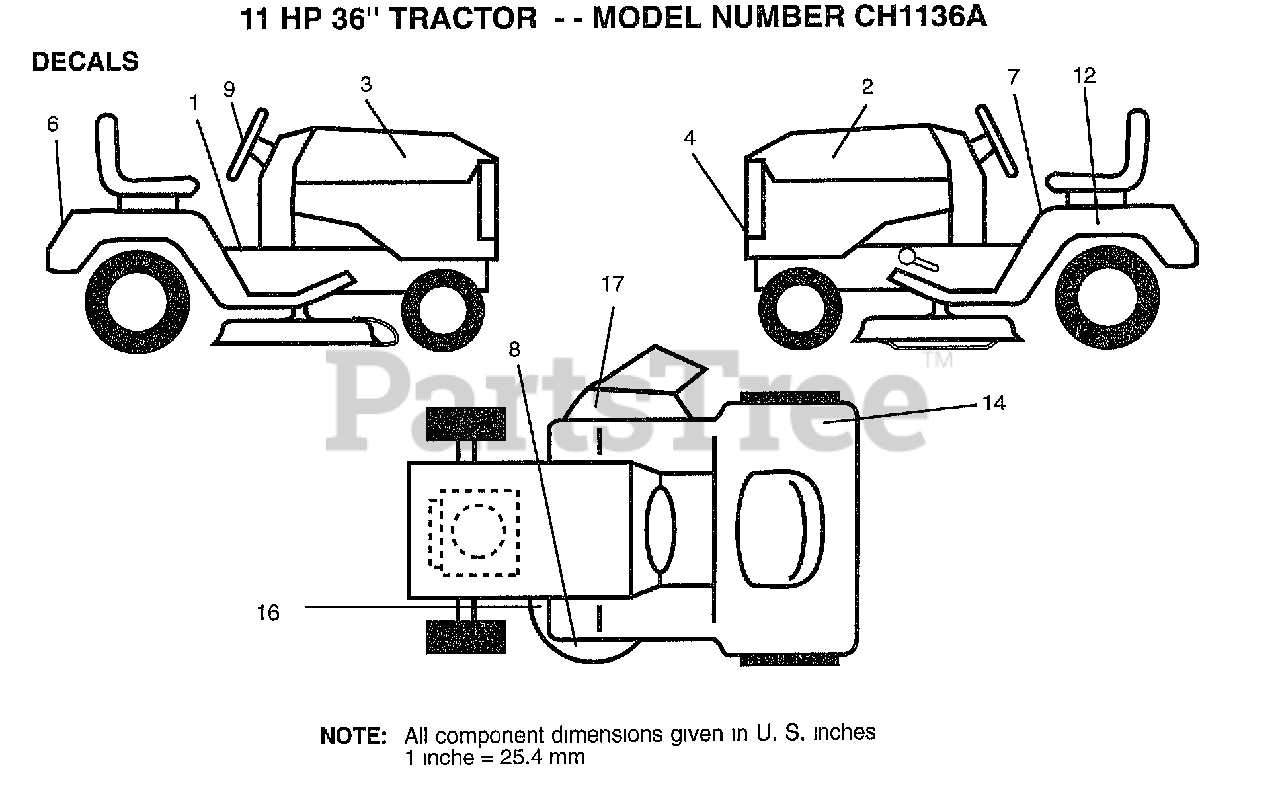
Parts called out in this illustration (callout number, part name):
1	DECAL.INST.OPER.
2	DECAL.HD.LH.CHAMP
3	DECAL.HD.RH.CHAMP
4	DECAL.GRILLE.CHAM
6	DECAL.FENDER
7	DECAL CAUTION
9	DECAL.INSRT.STRG
12	DECAL
16	"DECAL, WARNING"
17	DECAL.V.BELT
